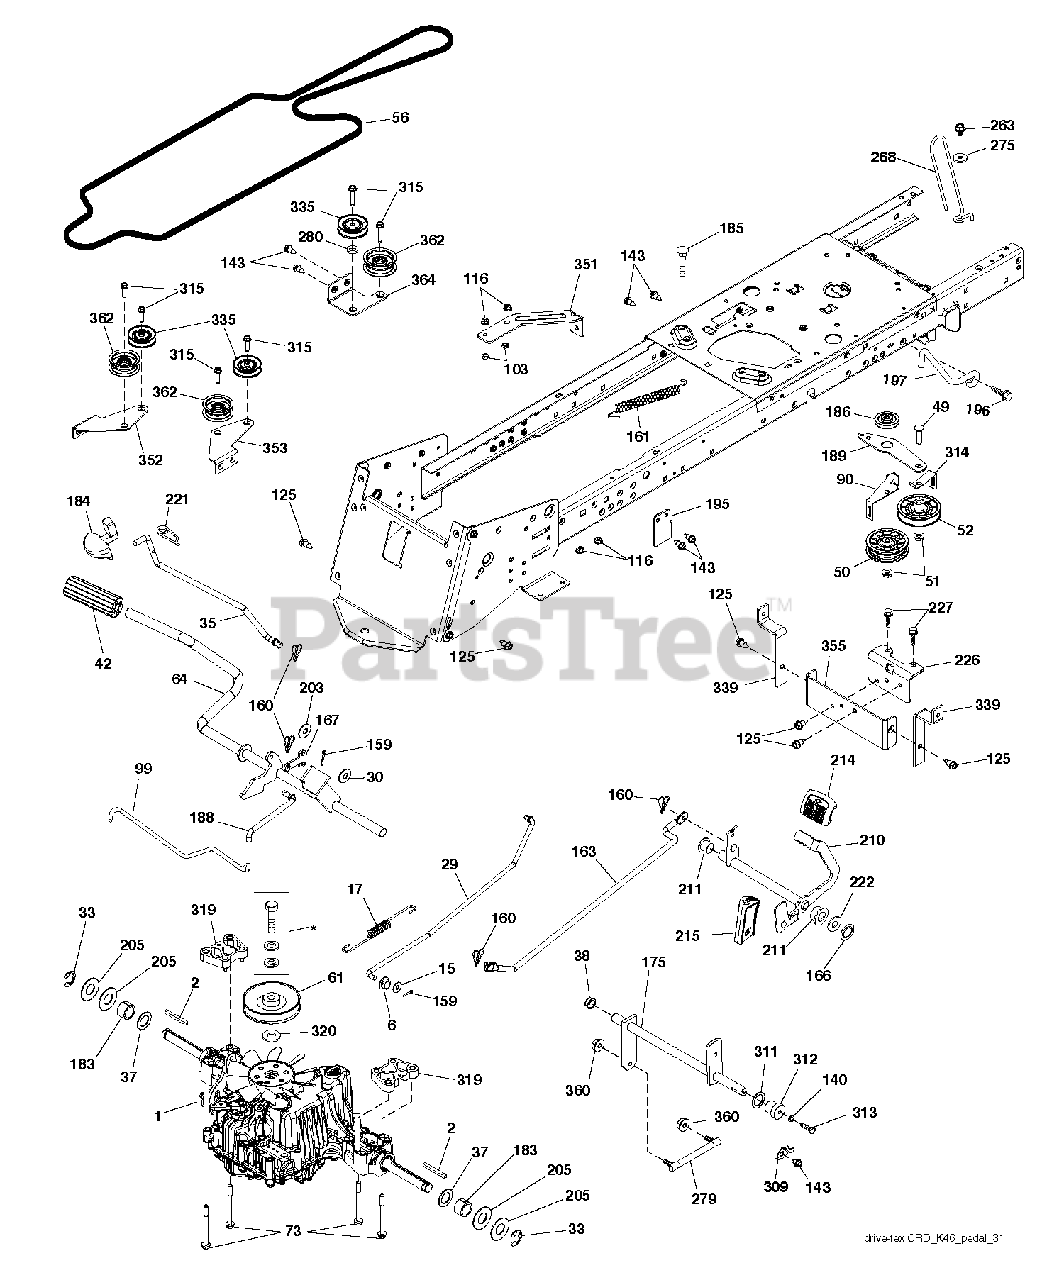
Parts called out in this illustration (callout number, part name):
2	SQUARE KEY
6	BUSHING.SNAP.NYL.BLK.
15	WASHER
17	SPRING
29	ROD
30	WASHER
35	ROD.CNTRL.PARK.PREDATOR.LT.TEX
37	WASHER.HARDENED
38	NYLINER SNAP 5/8" ID
42	PEDAL COVER T
50	IDLER.FLAT.910.OFFSET
51	NUT LOCK FLG 3/8-16 UNC
52	IDLER.V-GROOVE.910.OFFSET
56	V BELT DELV 113 K46 CRD
61	PULLEY
64	SHAFT.ASM.PEDAL.BRK.CNTR
73	BOLT.FLANGED
90	KEEPER KEEPER BELT CLUTCHING T
99	ROD ROD BYPASS CRD TEX GEN 2
103	JAM NUT TI
116	NUT LOCK HEX FLANGE 5/16-18
125	SCREW
140	LOCKWASHER
143	SCREW LT
159	COTTER PIN
160	RETAINER CLIP
161	SPRING, RETURN LT
163	ROD
166	NUT.PUSH.625
167	LATCH.BRAKE.SPRING
175	SHAFT SUBASM.SHAFT.CROSS.SHIFT
183	SPACER AXLE
184	HANDLE.PARKING.BRK.PRED.LT.RED
186	SPACER.RETAINER
188	RP LINK.CLUTCH.GROUND.DRIVE
189	BELLCRANK BELLCRANK GROUNDDRI
195	BRACKET.ROD.BRAKE
196	LINK.CLUTCH.ANIT-ROTAT
197	SCREW 3/8-16X1
203	WASHER
210	ROCKER.ASM.PEDAL.CONTR
211	BEARING.NYLON
214	PEDAL.FORWARD.PAD.TEX
215	PEDAL.COVER.REVERSE.CRD.X498GY
221	RETAINER.SPRING.CLIP.H
222	WASHER 21/32 X 1-1/4 X 10 GA.
226	BRACKET.MOUNT.TORQUE.K46.TLT
227	SCREW
263	SCREW, 3/8-16X3/4
268	GUARD MUFFLER
275	WASHER
279	LINK SUBASM. LINK AND STUD
309	PLATE.FASTENING.CROSS.SHAFT
311	WASHER NYL
312	HUB.TAPERED.ROUND.CRD
314	RETAINER KEEPER BELT
315	BOLT.5/16-18X1.25
319	SPACER SPACER TRANSAXLE TEX C
320	WASHER.SPACER.MANDREL
335	PULLEY.V-IDLER.
339	STRAP STRAP TORQUE K46 CRD TE
351	BRACKET BRACKET DECK SWAY
352	BRACKET BRACKET.IDLER
353	BRACKET
355	STRAP STRAP TORQUE K46 CRD TEX
360	NUT NUT HEX CENTERLOCK 5/16-24
362	IDLER.FLAT.2.25.INCH
364	BRACKET BRACKET IDLER CRD TEX
